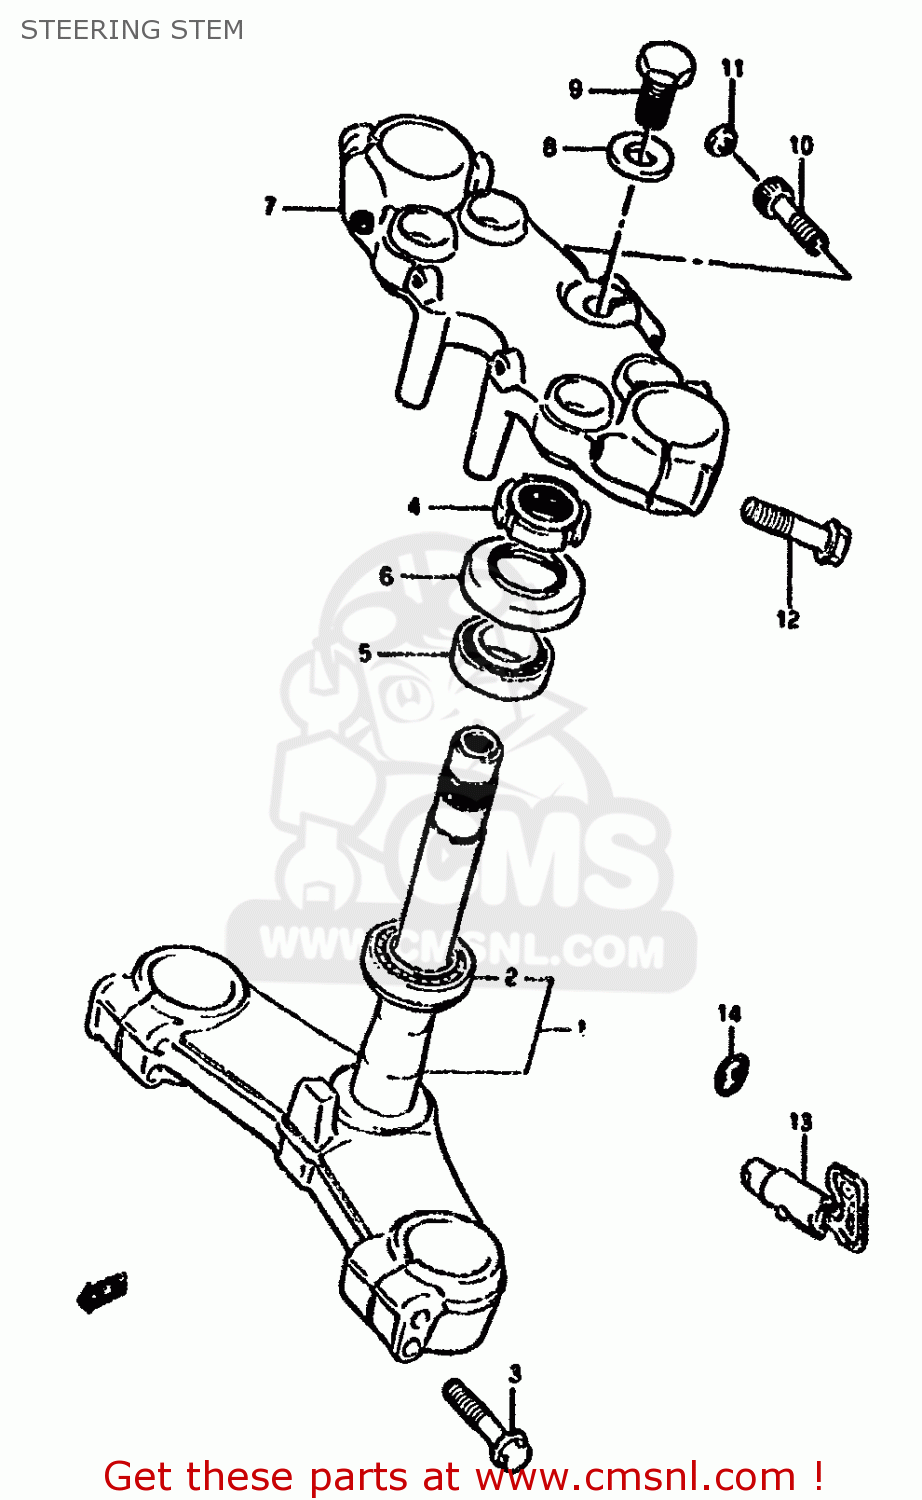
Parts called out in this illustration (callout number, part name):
1	STEM,STEERING
2	BEARING(30X55X17)
3	BOLT
4	NUT,STEERING STEM(25X44X10)
5	TAPER,ROLLER BEARING
6	DUST SEAL,STEERING UPR
7	BRACKET,UPR
8	WASHER,STEM HEAD
9	BOLT
10	BOLT, REAR (8X30)
11	CAP(OD:14.5)
12	BOLT 10X40
13	LOCK ASSEMBLY,STEERING (NEI
14	LABEL,STEERING LOCK
